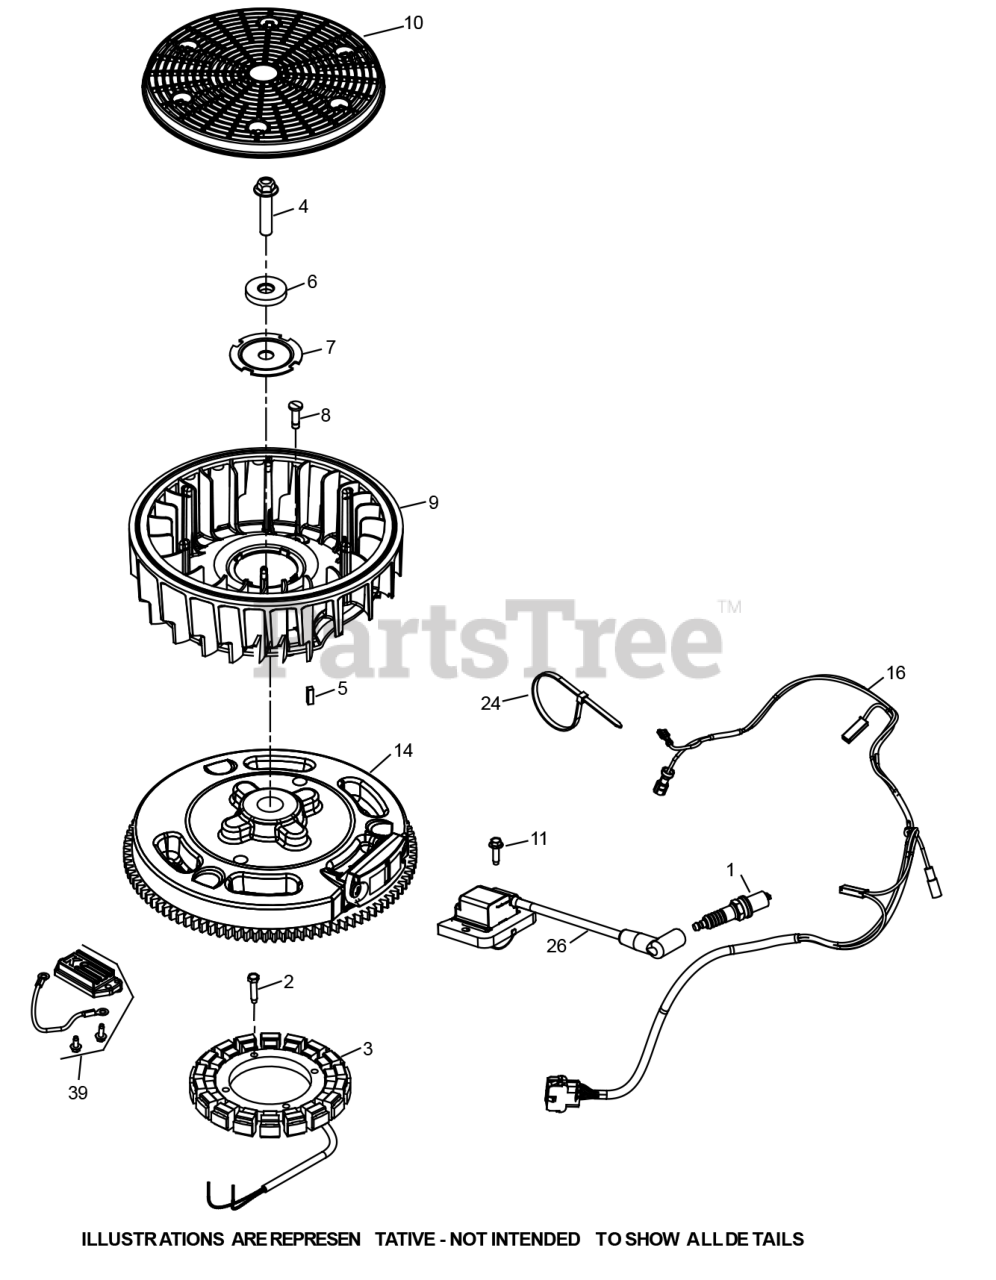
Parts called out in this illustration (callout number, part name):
1	SPARK PLUG RFI
2	THREAD FORMING SCREW
3	KIT-STATOR
4	HEX FLANGE BOLT
7	PLATE-FAN MOUNTING
11	THREAD FORMING SCREW
14	FLYWHEEL ASSEMBLY
16	WIRING HARNESS
26	IGNITION MODULE
39	REGULATOR RECTIFIER KIT
